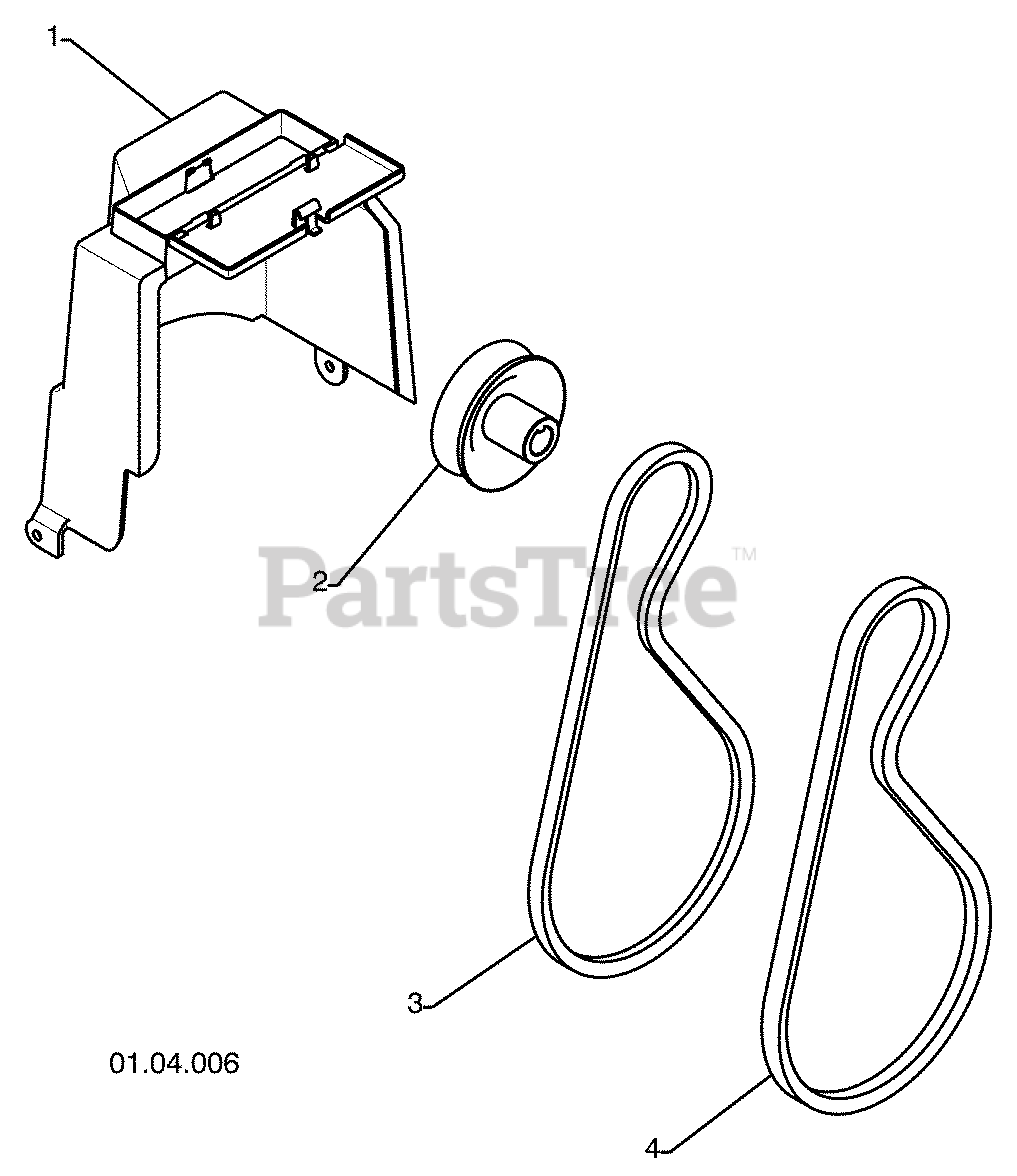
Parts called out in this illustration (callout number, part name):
1	COVER ASSEMBLY
2	PULLEY
3	TRACTION BELT
4	IMPELLER BELT
